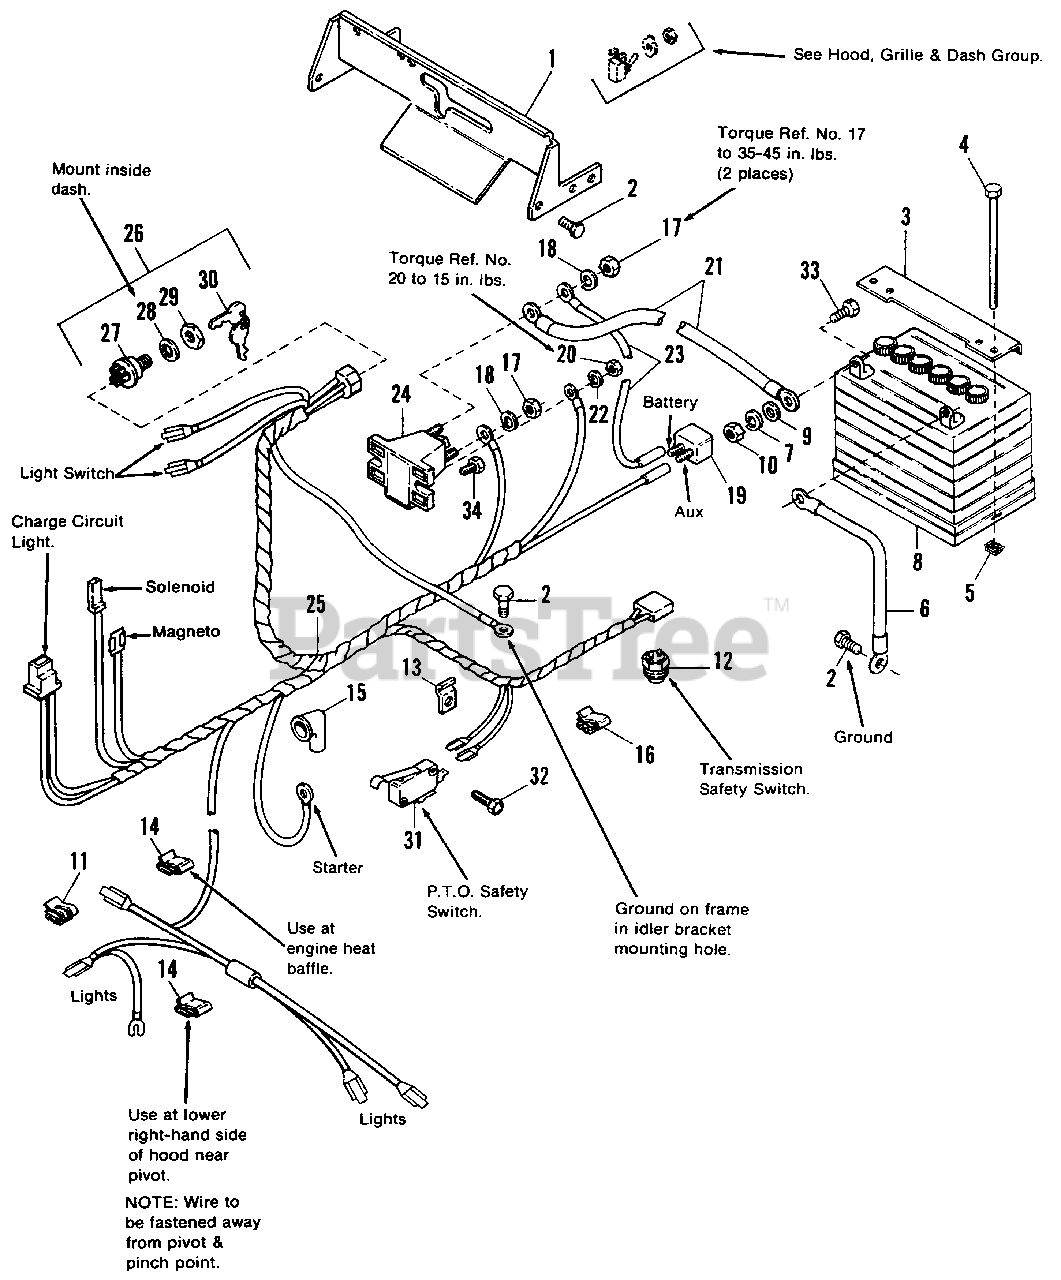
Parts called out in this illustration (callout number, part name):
1	QUADRANT, Shift
2	SCREW, Hex, Taptite, 1/4-20 x 3/8
3	HOLD DOWN, Battery
4	CAPSCREW, Hex Hd., 1/4-20 x 7
5	NUT, Retainer, 1/4-20
7	LOCKWASHER, 1/4
8	BATTERY SERVICE KIT, 39 Amp (includes decal)
9	WASHER, Plain
10	NUT, Hex, Full, 1/4-20
11	CLIP, Wire
12	SWITCH, Interlock
14	CLIP, Wire
15	COVER, Terminal
16	CLIP, Speed
17	NUT, Hex, Full, 5/16-18
18	LOCKWASHER, 5/16
19	BREAKER, Circuit
20	NUT, Hex, Full #10-32
22	LOCKWASHER, External, #10
24	SOLENOID
25	HARNESS, Wiring
26	SWITCH, Ignition (1690684, 1690849, 1690879 only)
26	SWITCH, Ignition (1690915, 1690934 only)
28	LOCKWASHER, Internal, 5/8
29	NUT, Hex, 5/8-32
31	SWITCH, P.T.O., Interlock
32	SCREW, Taptite, #5-40 x 3/4
33	CAPSCREW, 1/4-20 x 3/4
34	SCREW, Taptite, 1/4-20 x 3/4
